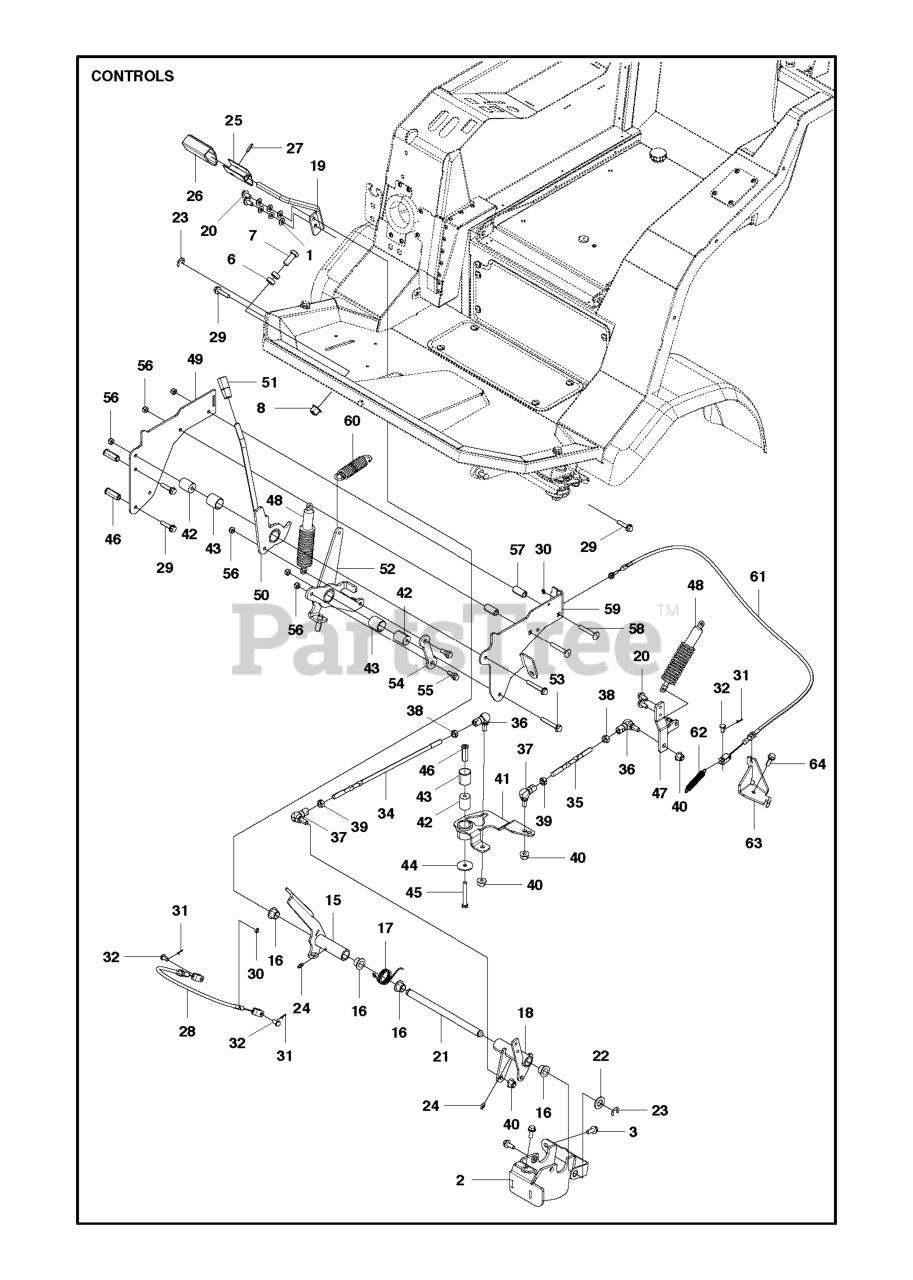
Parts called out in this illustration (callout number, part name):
1	WASHER BRB 8.4X17
16	BUSHING
24	GREASE NIPPLE
26	PEDAL RUBBER
29	SCREW EHHFM
31	Cotter Pin
32	Clevis Pin
43	BUSHING
48	SHOCK ABSORBER
53	SCREW EHHFM
56	LOCKNUT M8
64	BOLT
